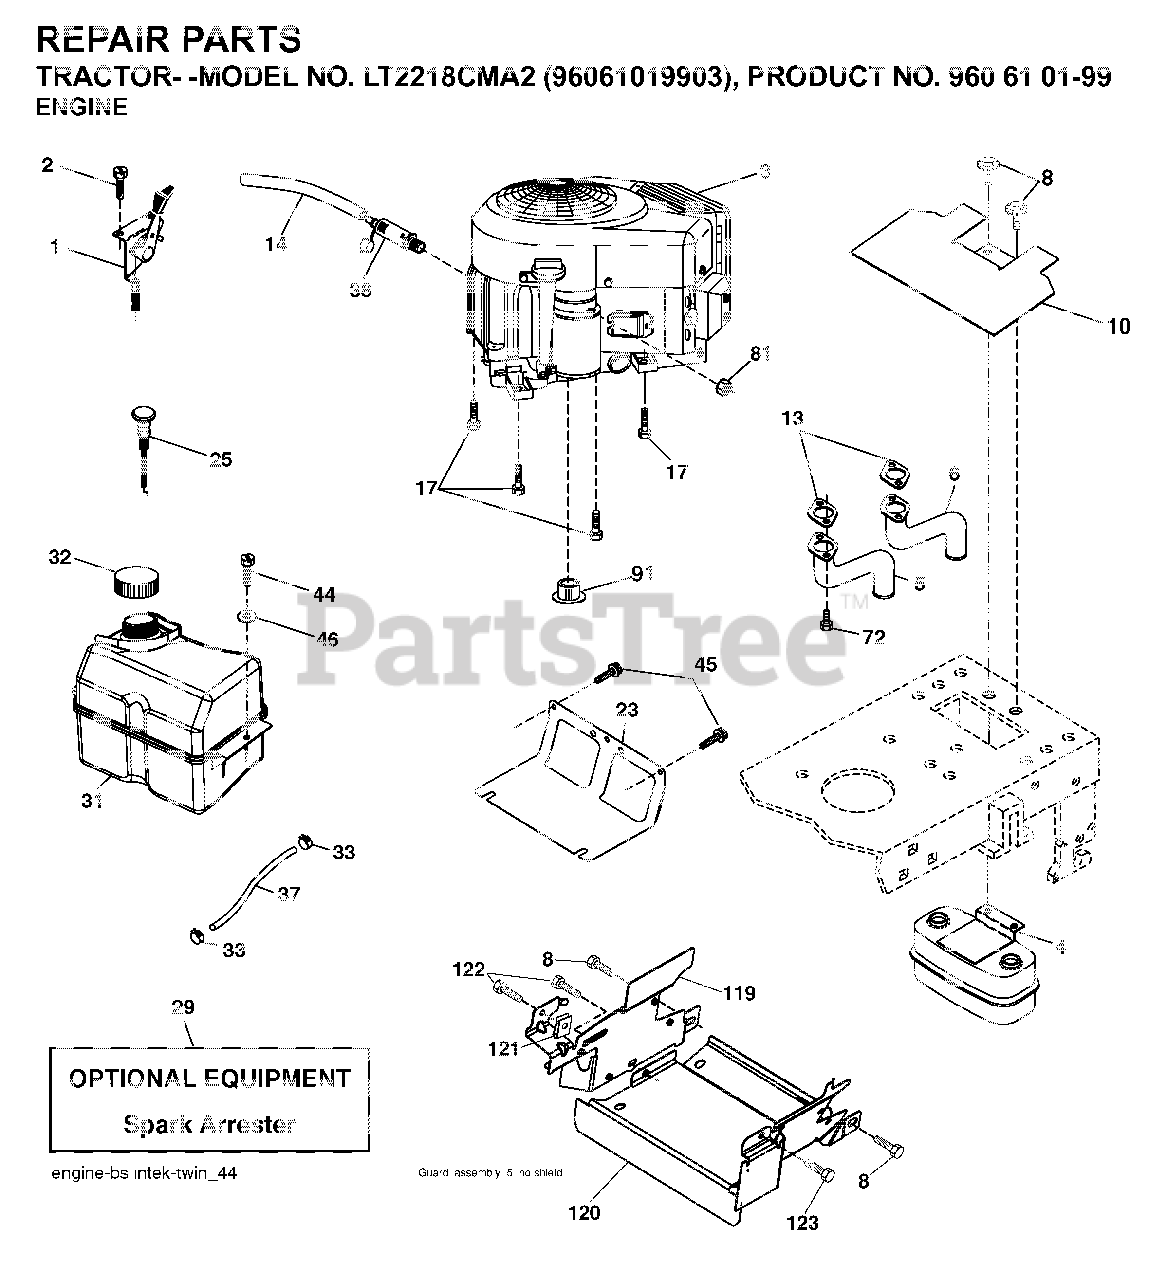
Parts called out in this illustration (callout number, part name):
1	THROTTLE CABLE
2	SCREW
4	MUFFLER.TWIN.CYL.LOW.TONE
5	EXHAUST TUBE RH
6	TUBE MANIFOLD LH
8	BOLT, 5/16-18 X 1 3/4
10	RP SHIELD HEAT MUFFLER
13	GASKET.MUFFLER
14	TUBE, DRAIN OIL ASM.
17	SCREW.3/8-16
23	SHEILD.BROWNING.DBR.GUARD
25	CONTROL CHOKE
29	ARRESTER SPARK (OPTIONAL)
31	TANK FUEL
32	FUEL CAP
33	HOSE CLAMP
37	LINE.FUEL.20
38	PLUG DRAIN OIL EASY
44	SCREW HEXWSHR 1/4-20X3/4
45	SCREW, 3/8-16X3/4
72	SCREW.SOCKET.HEAD.5/16-18
81	NUT
91	BUSHING.1.375OD
122	SCREW.1/4-20X5/8
123	SCREW, 5/16-18 X 1/2
